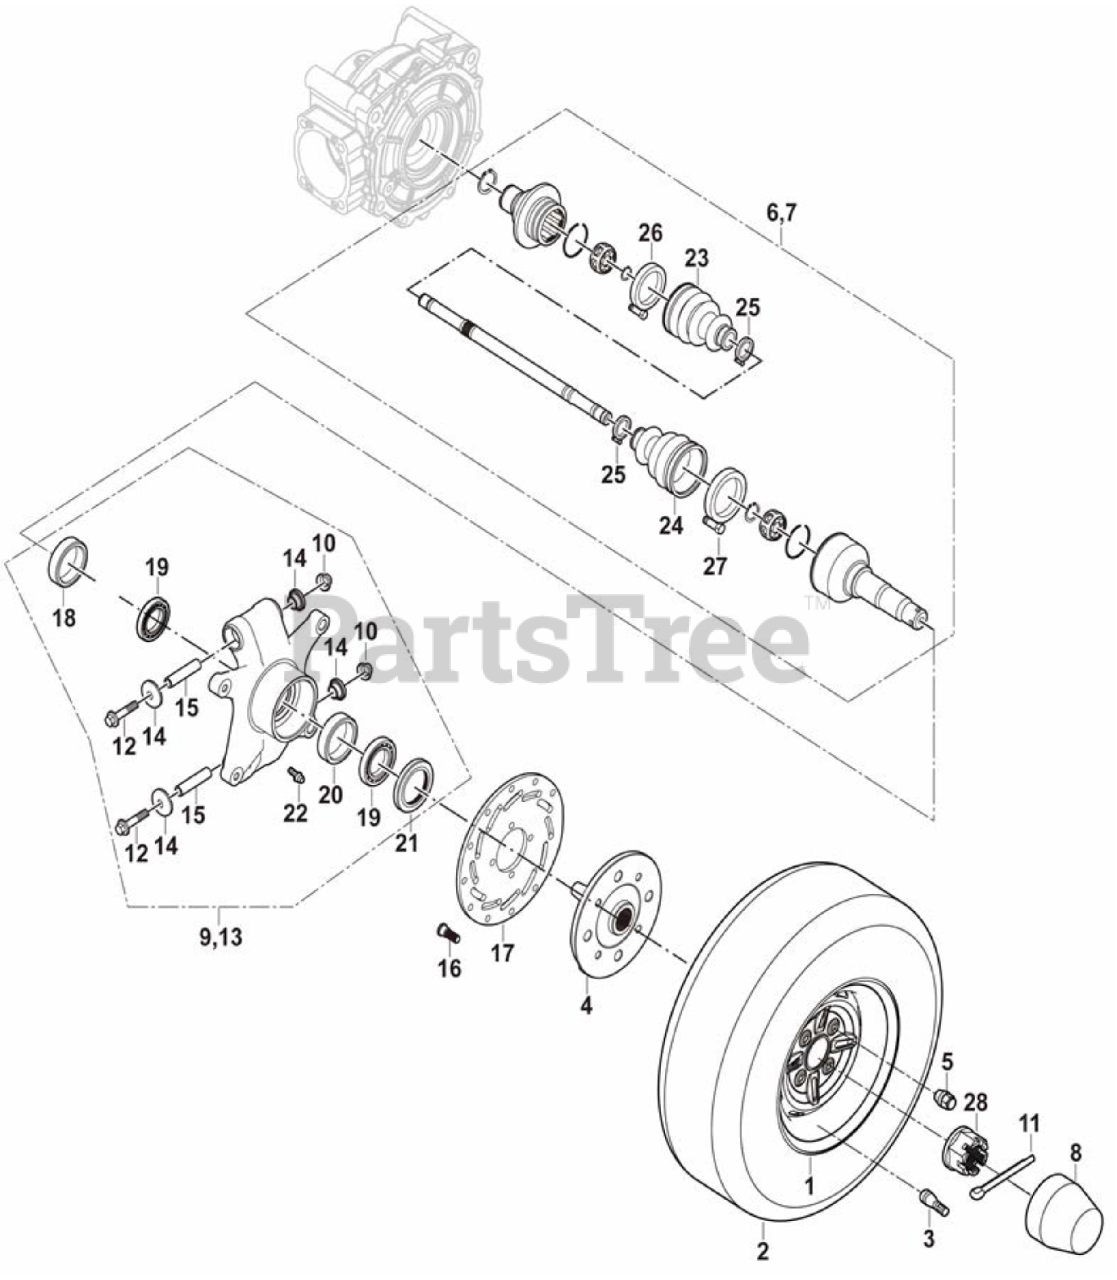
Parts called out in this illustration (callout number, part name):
3	valve core
4	Connecting base assy,rear hub
5	Taper nut M10X1.25
6	Rear Left Semiaxle U
7	Rear Right Semiaxle U
8	trim cover F, wheel shaft
9	Front Right Knuckle
10	Hexagon Flange Self-Lock Nuts M10x1.25
11	Cotter pin 3X40
12	Hexagon Flange Bolt M10X1.25X105
13	Front Left Knuckle
15	Knuckle bearing sleeve line
16	Inner hexagon cone bolt with pan M8
17	Rear Brake pad
18	Rear Knuckle inside oil seal 38X62X8
19	Rear Knuckle bearing
20	Knuckle bearing spacer bush
21	Rear Knuckle outside oil seal 42X62X7
22	Knuckle oil fitting
23	Axle rubber boot H
24	Axle rubber boot G
25	Axle rubber boot clamp N
26	Axle rubber boot clamp P
27	Axle rubber boot clamp M
28	Hexagon Thin Slotted Nut M24X1.5
